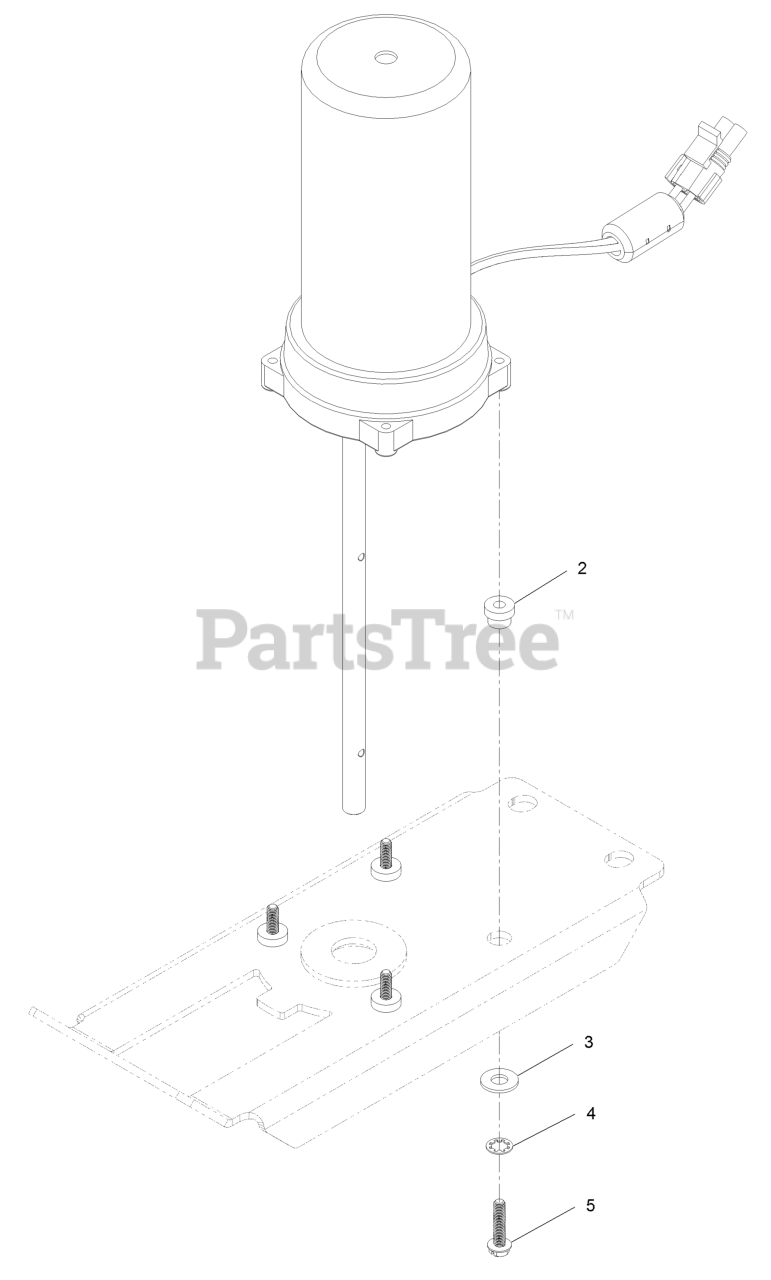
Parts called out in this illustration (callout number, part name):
3	WASHER-FLAT
4	WASHER-LOCK, INT
5	SCREW-SHWH
